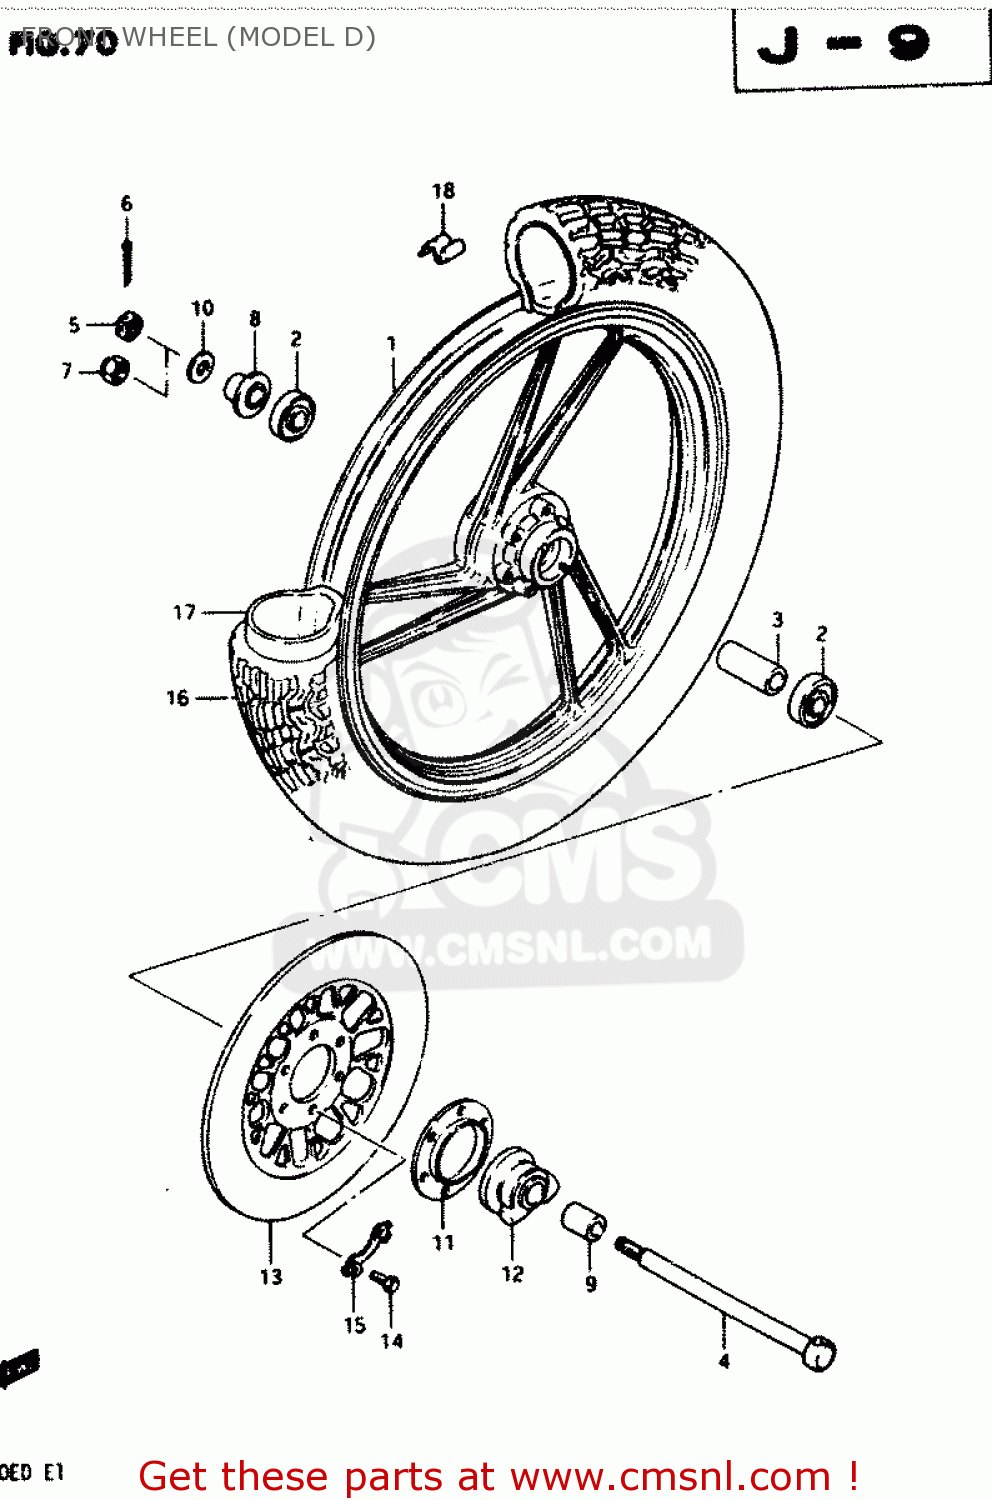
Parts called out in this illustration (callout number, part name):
1	WHEEL (1.60X18)
2	BEARING
3	SPACER(15.3X21.7X63)
4	AXLE,FRONT
5	NUT 12MM
6	COTTER PIN
7	NUT
8	SPACER, BEARING RH
9	SPACER(15X22X30)
10	WASHER
11	DUST SEAL,SPEEDOMETER GEAR BOX
12	BOX ASSY,SPEEDOMETER GEAR
13	DISC,FR BRAKE
14	BOLT(8X25)
15	WASHER
16	TIRE,FRONT
17	TUBE,INNER
18	BALANCER,WHEEL
